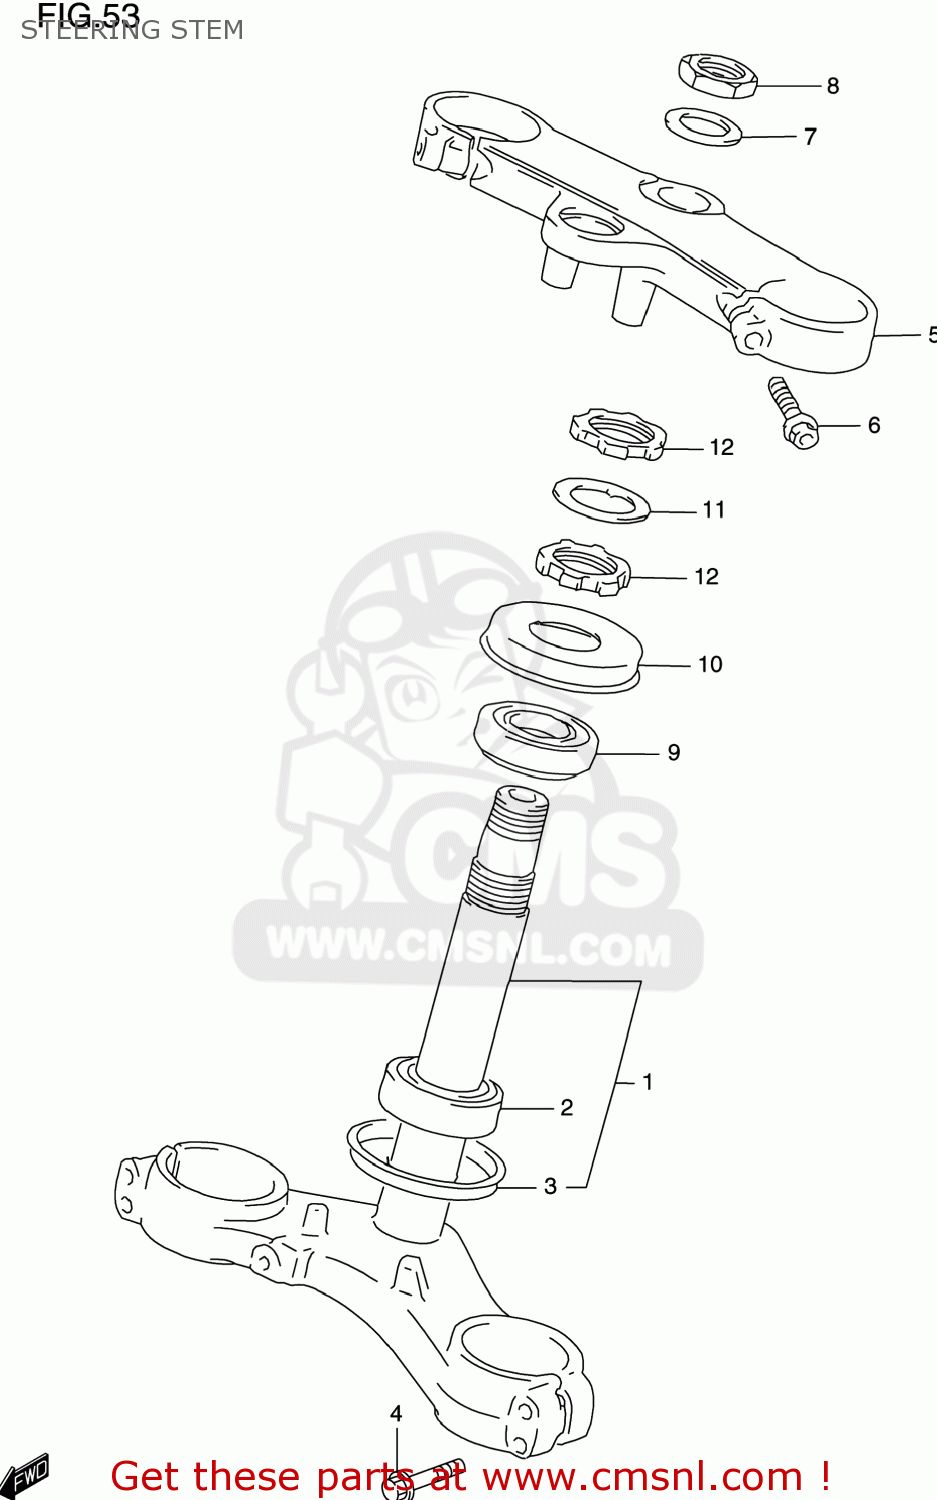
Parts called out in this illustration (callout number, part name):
1	STEM,STEERING
2	BEARING(30X55X17)
3	SEAL,STEERING LWR
4	BOLT
5	HEAD,STEERING STEM
6	BOLT
7	WASHER
8	NUT,STEM HEAD
9	BEARING(30X55X17)
10	SEAL,STEERING UPR DUST
11	WASHER,STEERING STEM
12	NUT,STEERING STEM
